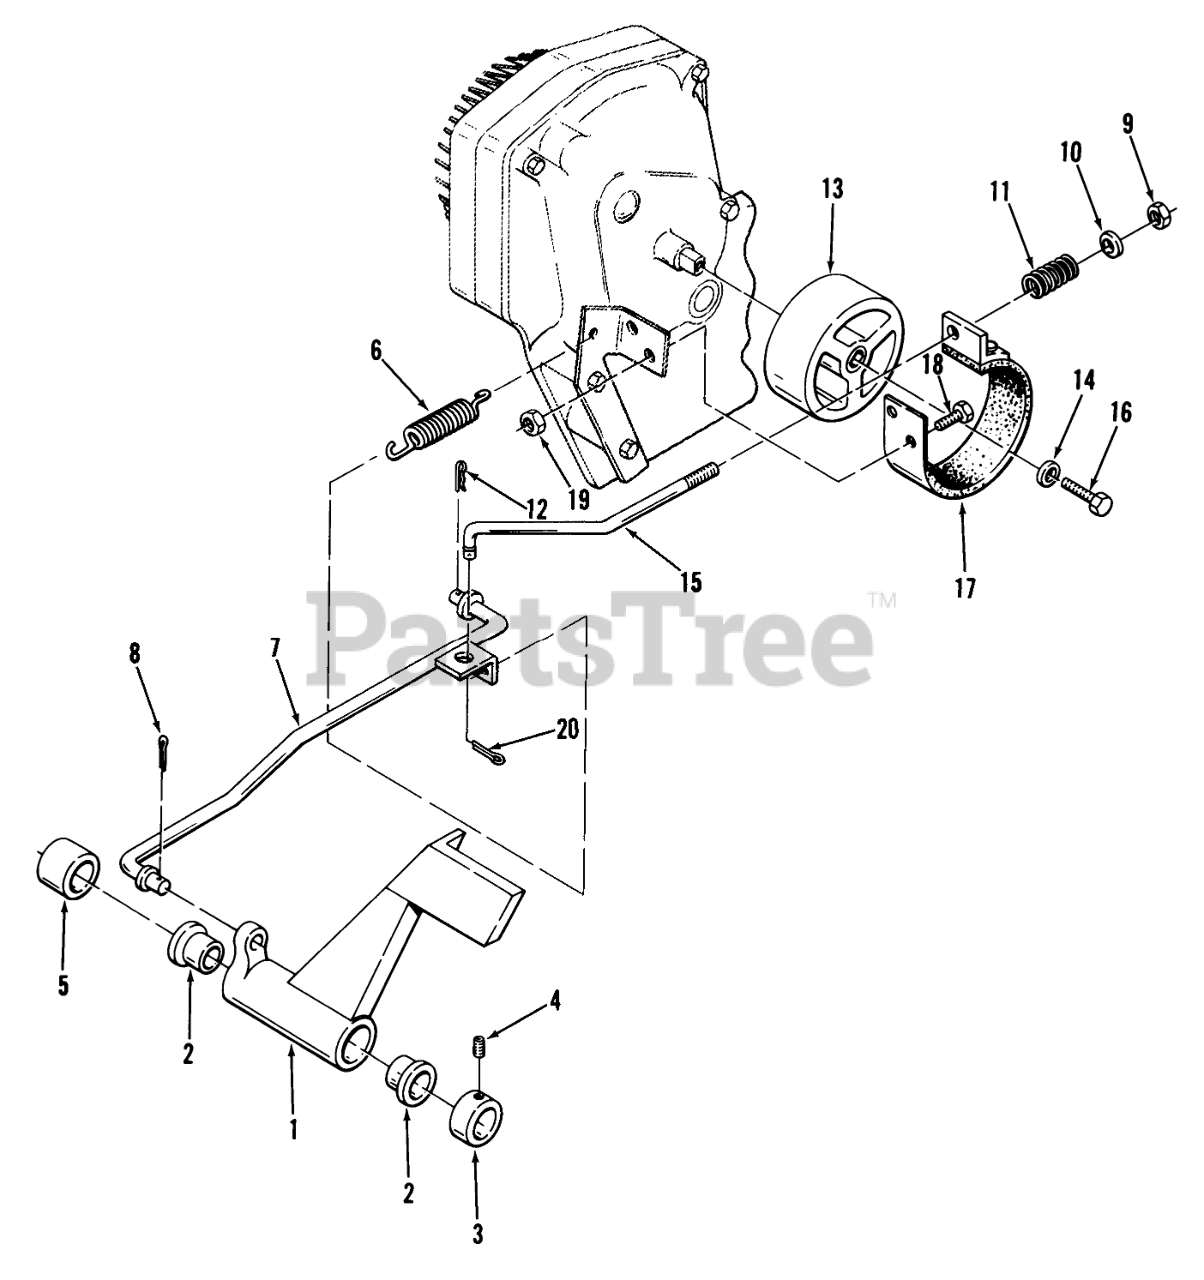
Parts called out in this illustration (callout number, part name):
1	PEDAL R
2	BUSHING
3	Collar
4	SCREW-SET
5	Spacer
6	SPRING-EXTENSION
7	Brake Rod-Front
9	NUT
10	Washer
11	SPRING-COMPRESSION
13	DRUM-BRAKE
14	WASHER -4
15	Brake Rod-Rear
16	BOLT
17	BRAKE BAND ASM
18	Bolt
19	Nut
20	Pop Rivet
